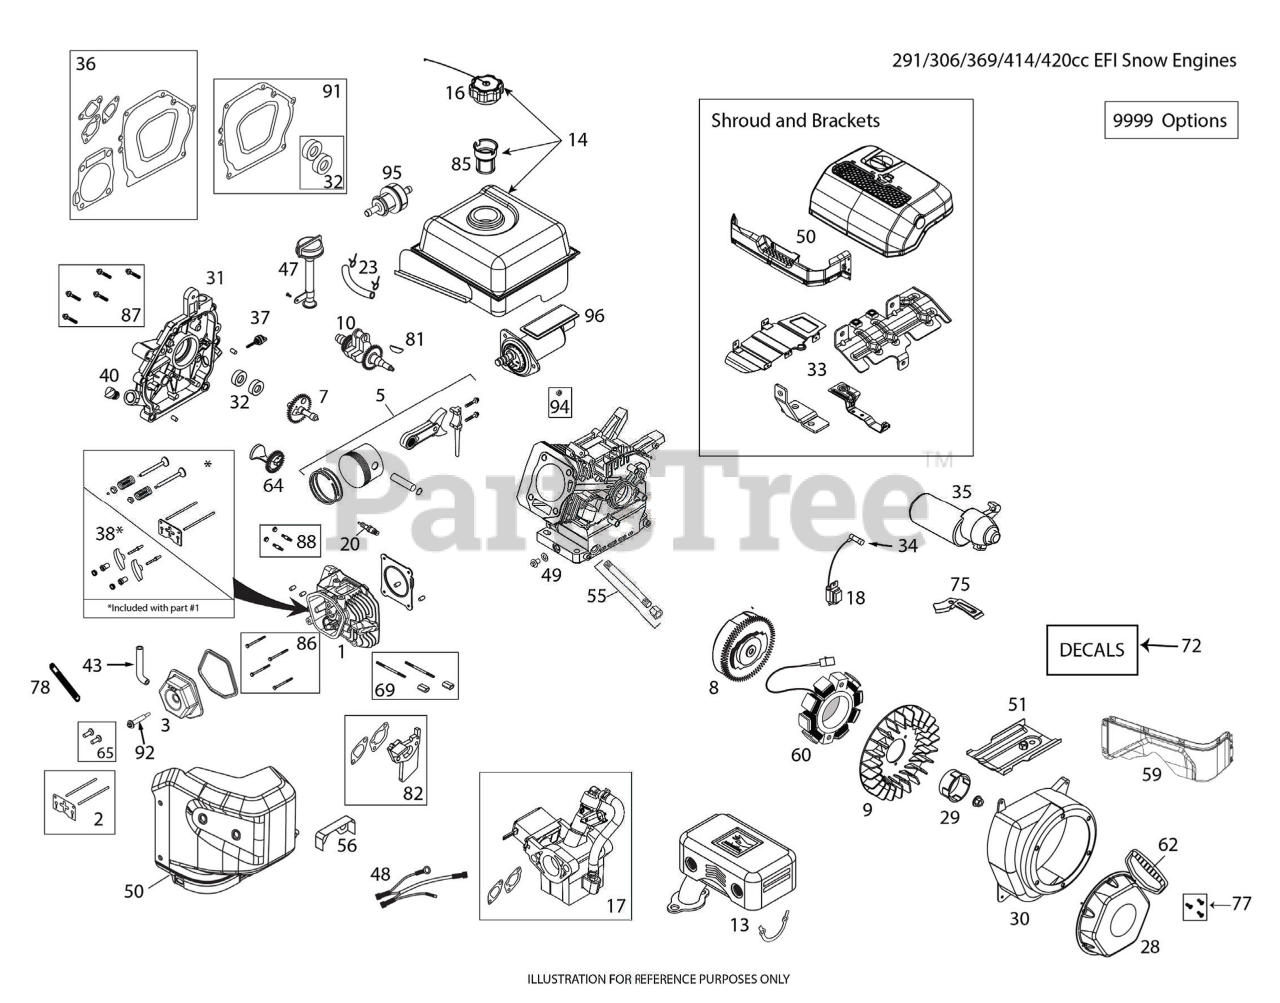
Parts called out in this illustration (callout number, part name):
2	PUSH ROD TAPPET KIT
3	VALVE.COVER.LCT.414CC.
8	FLYWHEEL.EL.ST.SKSNO2401.1
9	FLYWHEEL.FAN
10	CRANKSHAFT
18	IGNITION.COIL.(CDI).291-414CC
20	SPARK.PLUG(2083810)
20	PLUG.SPARK
23	Fuel Hoses
28	STARTER RECOIL.291/306CC.LCT
29	STARTER CUP.LCT.291/306CC
32	OIL.SEAL.KIT(SK2913900)
34	SPARK.PLUG.BOOT.SNW,SKSN4691.1
37	DIPSTK.OIL.BLK.LCTSK4143711.1
38	ROCKER ARM KIT
40	NONREMVABLE.OIL.PLUG(SK4143715
43	TUBE.BREATHER.LCT.219CC/414CC
49	OIL.DRAIN.PLUG
55	OIL PIPE DRAIN EXTENDED.LCT SK
60	Charging Station
62	HANDLE.RECOIL.DELUXE.LCT
65	TAPPET KIT.LCT.SK2911005.1
75	WIRE GUARD
77	BOLT.KIT.RECOIL.LCT.ALL.ENGINE
78	STRAP.RETAINING.TUBE.BREATHER.
81	KEYS.FLYWHEEL.136/291CC.5PACK
82	SPACER.CARBURETOR.414CC.LCT
85	STRAINER.FUEL.TANK.LCT.208CC
86	KIT.BOLT.CYLINDER.HEAD.(4PC)
87	KIT.7-BOLT.CRANKCASE.CVR.291CC
91	GASKET KIT CRANKSHAFT.LCT
92	CENTER VALVE COVER BOLT
